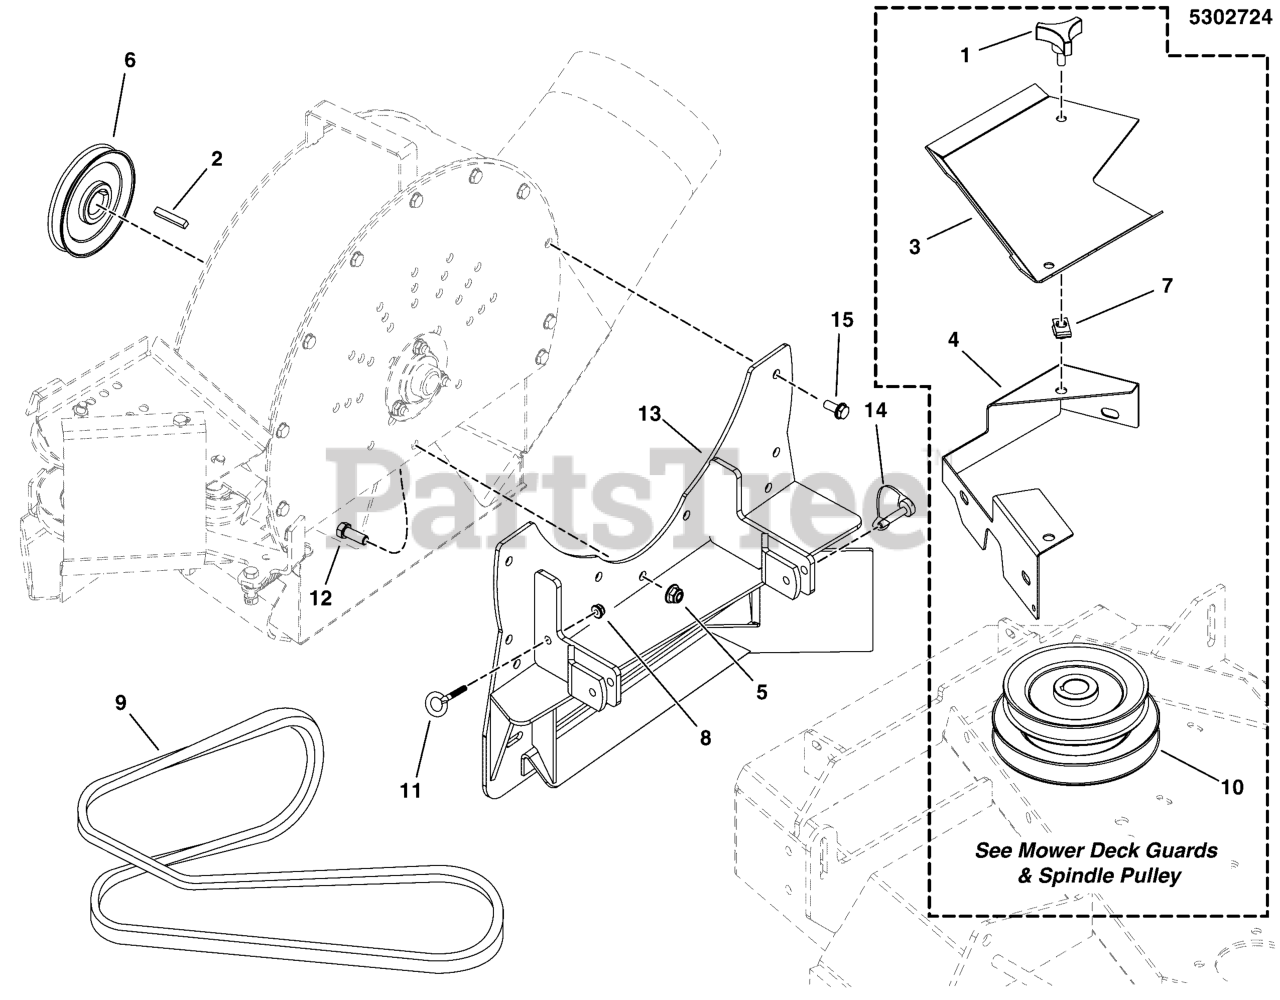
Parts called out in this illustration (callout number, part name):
1	KNOB, PLASTIC, 5/16-18 X 3/4
2	KEY 1/4 SQ X 1 1/2 LONG
3	SEE MOWER DECK GUARDS & SPINDLE PULLEY
4	SEE MOWER DECK GUARDS & SPINDLE PULLEY
5	NUT, 3/8-16 HEX NYLOCK FLANGE
6	PULLEY, BLOWER AXLE, 48
7	BODY CLIP, 5/16-18-7GA MATERIAL
8	NUT, 1/4-20 HEX NYLOCK FLANGE
9	BELT, A-SEC, 92.00EL, ARAMID, WRPD
10	SEE MOWER DECK GUARDS & SPINDLE PULLEY
11	EYE BOLT, 1/4-20 X 2.5, 1THRD, .5EYE,CZ
12	BOLT, 3/8-16 X 1" GD5 CZ
13	WELD, BLOWER MOUNT, 48 ICD - BLK
14	SNAPPERPIN, 5/16 X 2
15	BOLT, 5/16-18 X 5/8" Self Lock
